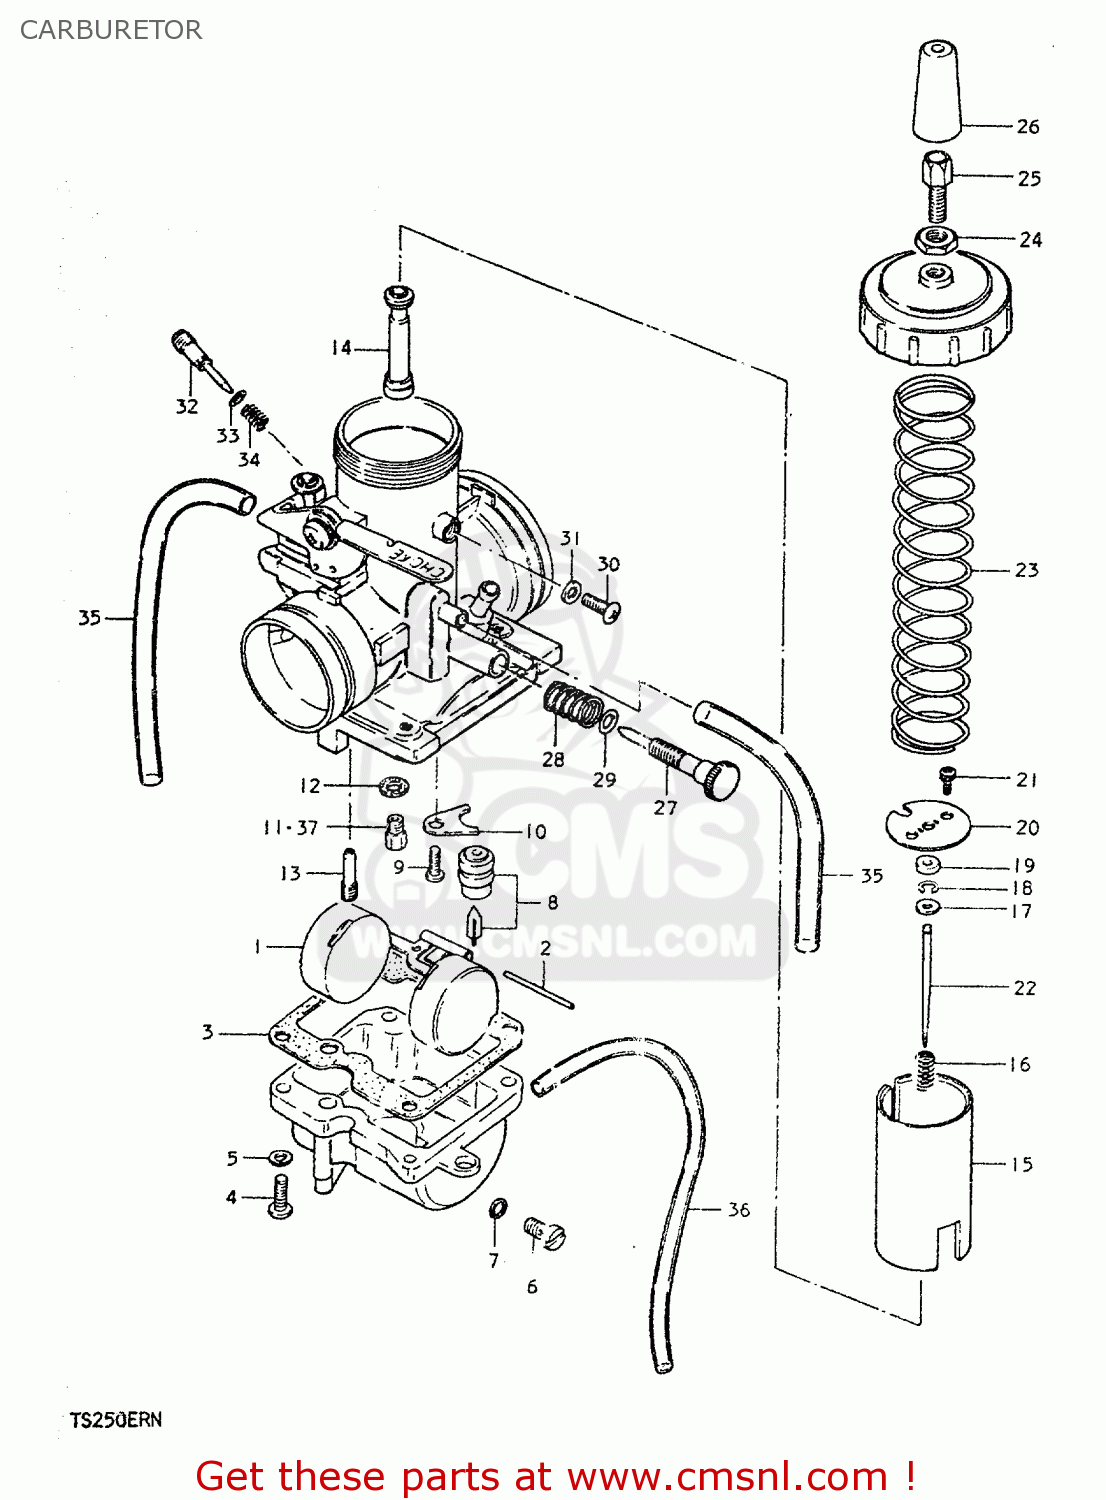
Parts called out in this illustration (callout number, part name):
1	FLOAT
2	PIN,FLOAT
3	GASKET,FLOAT CAHMBER (NAS)
4	SCREW
5	LOCK WASHER
6	PLUG
7	GASKET,DRAIN,PLUG (NAS)
8	VALVE ASSEMBLY,NEEDLE
9	SCREW
10	PLATE
11	JET
12	WASHER
13	JET
14	JET,NEEDLE
15	VALVE,THROTTLE
16	SPRING
17	WASHER,JET NEEDLE
18	CLIP
19	RING
20	PLATE
21	SCREW
22	NEEDLE,JET
23	SPRING, THROTTLE VALVE
24	NUT
25	ADJUSTER,CABLE
26	CAP
27	ADJUSTER
28	SPRING
29	O-RING
30	SCREW
31	RING
32	SCREW,PILOT AIR
33	O RING
34	SPRING
35	HOSE
36	HOSE
37	JET
